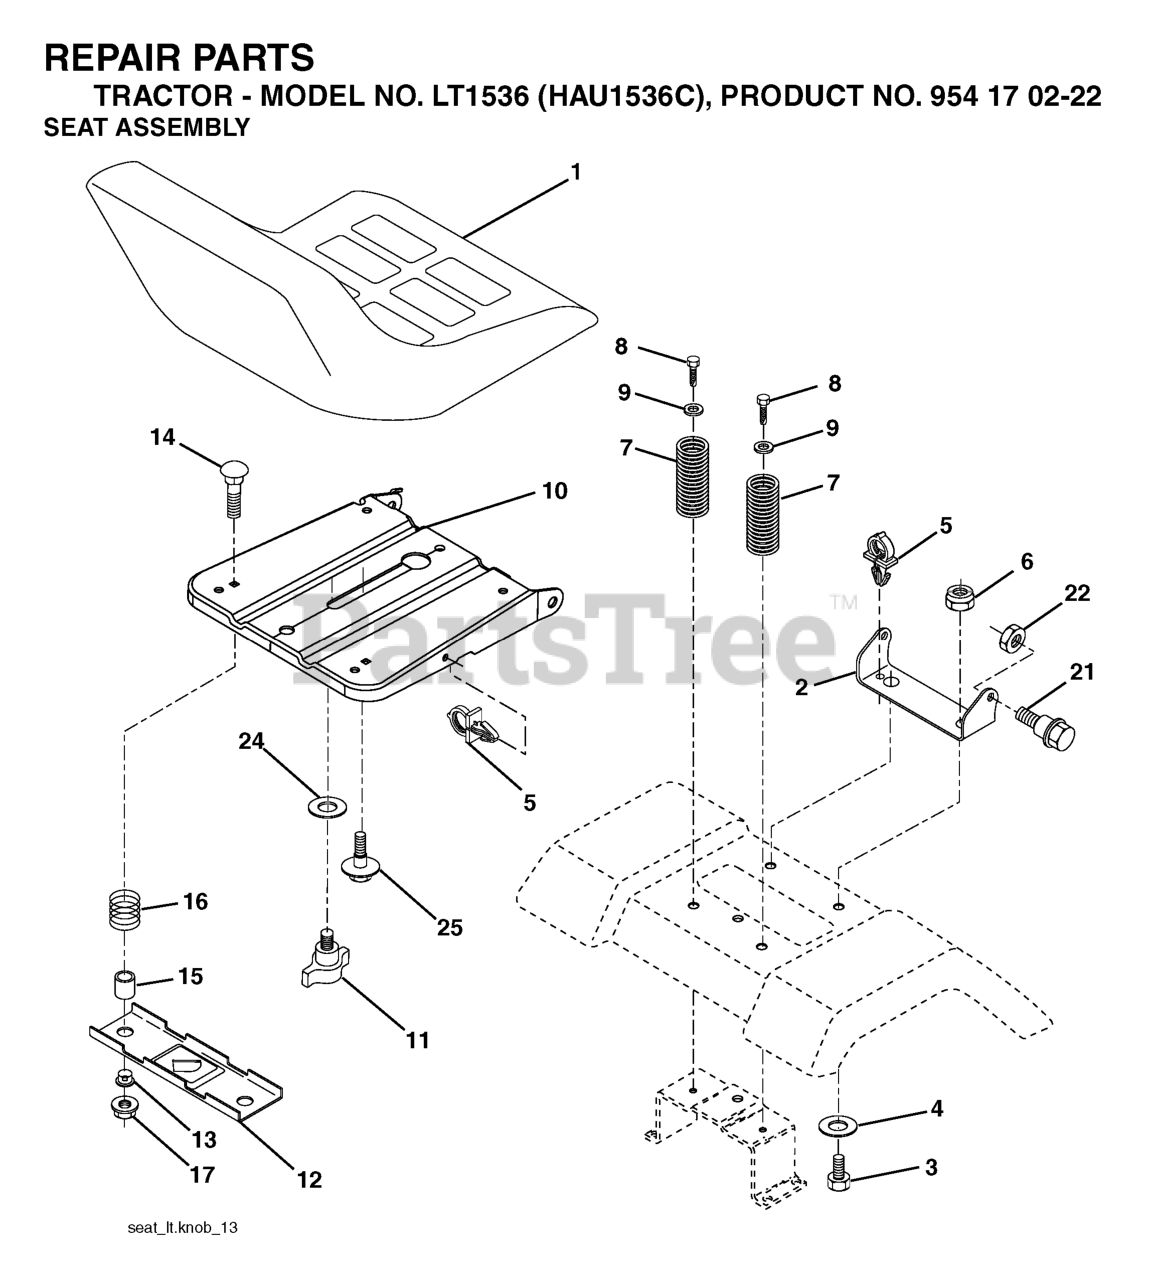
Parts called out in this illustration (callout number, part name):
1	RP SEAT
2	SEAT PIVOT BRKT
3	BOLT, HEX 3/8-16X1
6	NUT
7	SPRING COMPRESSION
8	SCREW 3/8-16X1
9	WASHER
10	PAN SEAT
11	KNOB.SEAT.ADJ.WINGNUT
12	BRKT SWITCH
14	BOLT.ROUND.HEAD.SQUARE.NECK
15	SPACER SPLIT 28X.96
17	NUT T
21	BOLT.SHOULDER.5/16-18
22	NUT.71038.31-18.HEX.NYLOCK
25	BOLT,SHOULD
